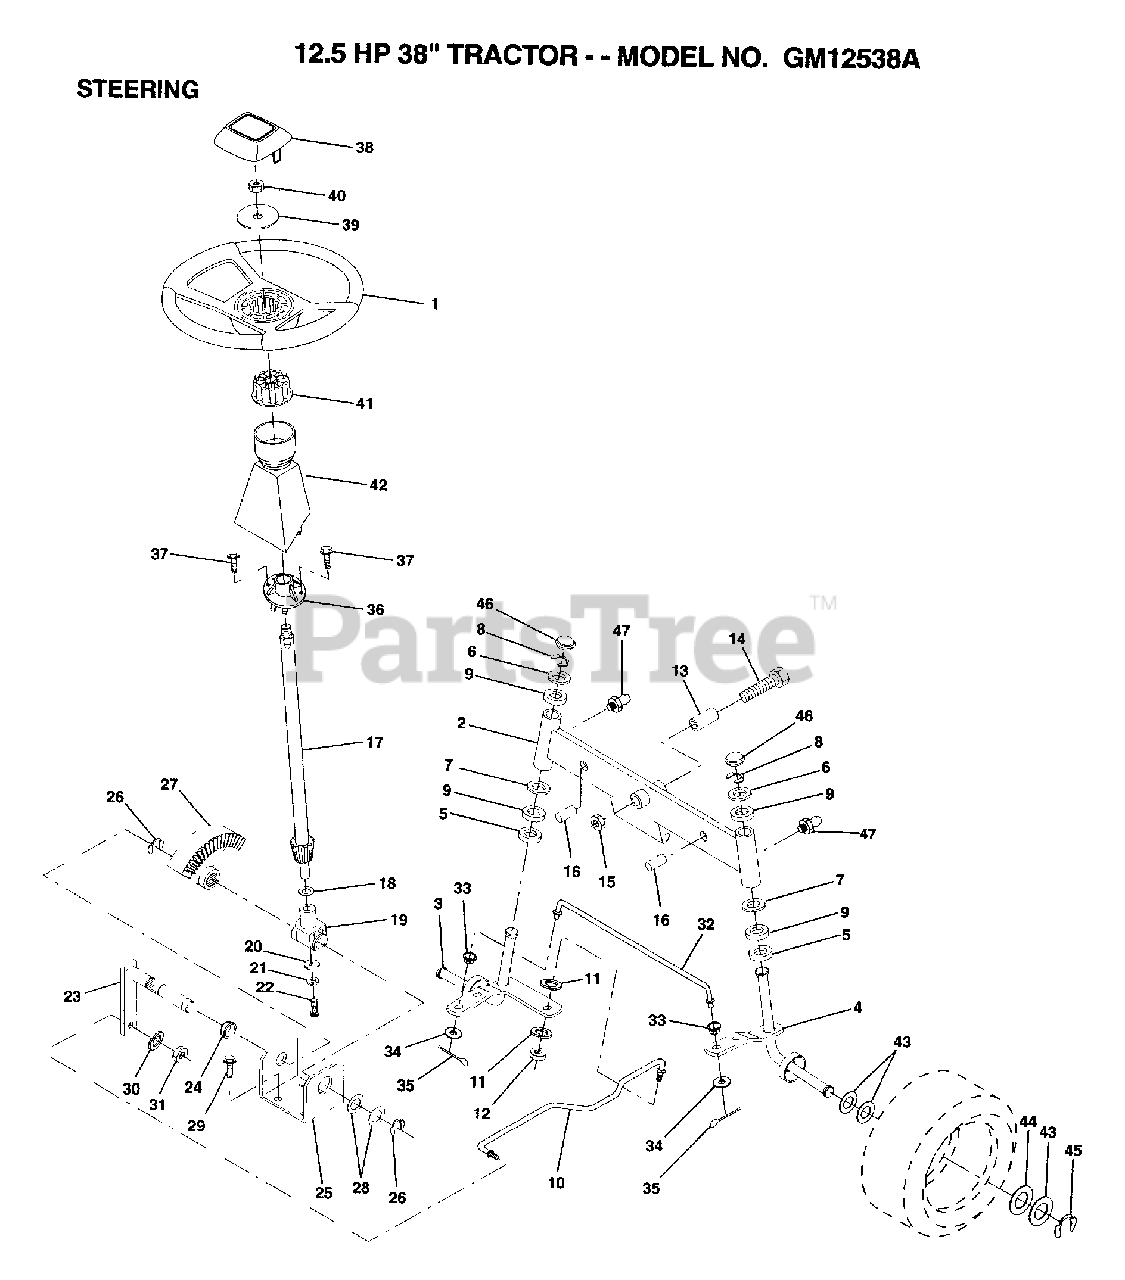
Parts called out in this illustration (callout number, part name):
3	SPINDLE LH
4	SPINDLE RH
5	WASHER .T
6	WASHER
7	WASHER
8	RING
9	COL. SRTG. BEAR.
11	LOCKWASHER
13	BEARING
14	BOLT HEX 5/8-11
15	"NUT-LOC,FLANGE LT"
16	AXLE PIN
17	SHAFT ASM
18	THRUST WASHER
19	SUPPORT.SHAFT
21	LOCKWASHER
22	"SCREW,SPECIAL"
24	NYLINER T
25	"BRKT,STEERING"
26	RING
27	GEAR SECTOR
28	WASHER .T
29	SCREW
30	LOCKWASHER
32	TIE ROD
33	BUSHING.DRAGLINK
34	WASHER
35	COTTER PIN
38	ST WHL INSERT CAP
39	WASHER T
40	GRIPCO NUT
41	ADAPTER-WHEEL LT
42	"TUBE, STR SHAFT"
43	WASHER
44	WASHER
45	RING
46	CAP
47	ZERK M
